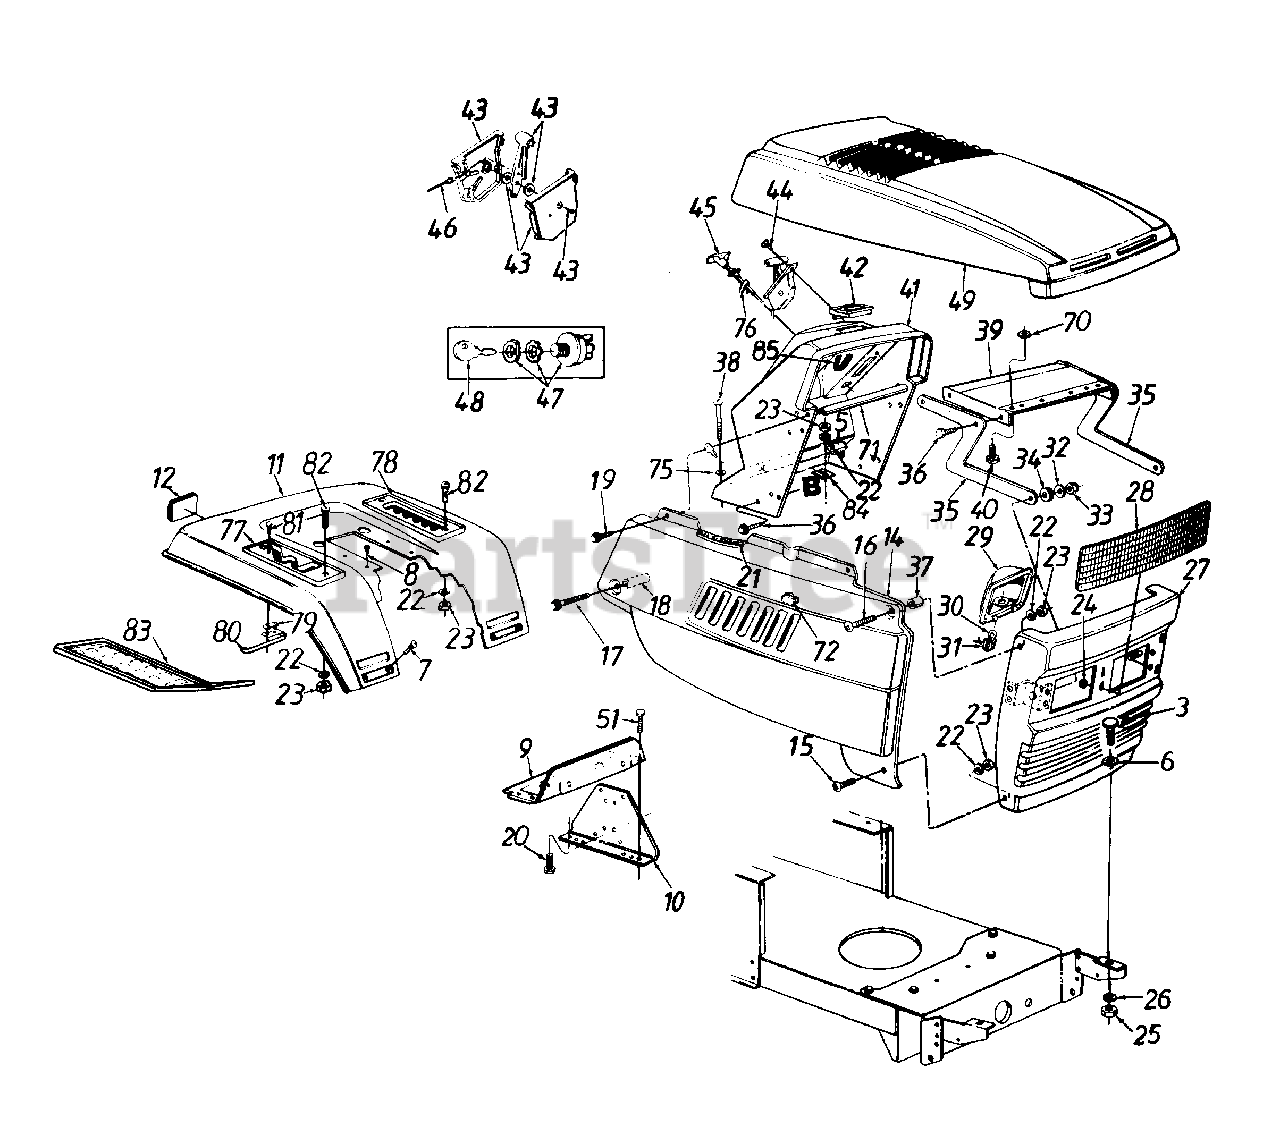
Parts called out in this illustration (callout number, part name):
3	Hex Bolt 5/16-18 x .75" Lg.
5	Light Switch
6	Fl-Wash. .344" I.D. x 1" O.D.
7	Carriage Bolt 1/4-20 x .5" Lg.
8	Hex Wash. Hd. Tap Scr. 5/16 x .75" Lg.
9	Support Bracket
14	Side Panel - R.H.
15	Truss Mach. Scr. 1/4-20 x .5" Lg.
16	Truss Mach. Scr. 1/4-20 x 1.0" Lg.
17	Hex Wash. TT-Tap Scr. 1/4-20 x 1.75" Lg.
18	Spacer .26" I.D. x 1.32"
19	Hex Rolling tap Scr. 1/4-20 x .75" Lg
20	Hex Bolt 1/4-20 x .62" Lg.
21	Trim Strip - 18" Lg.
22	L-Wash. 1/4" I.D.
23	Hex Nut 1/4-20 Thd
24	Speed Nut 5/16" Thd.
29	Headlamp Housing
30	Headlamp
31	Twist Lock Lamp Socket
32	Bell-Wash. .345" I.D. x .88"
33	Hex L-Nut 5/16-18 Thd.
34	Rubber Washer
37	Spacer .262" I.D. x .31"
38	Carriage Bolt 1/4-20 x 1.25" Lg.
41	Dash
42	Ammeter
43	Throttle Control Box Ass'y.
44	Mach. Scr. #10 x .44" Lg.
45	Choke Control
46	Throttle Control Wire
47	Ignition Switch
48	Ignition Key
49	Hood
51	Hex Wash. Hd. B-Tap Scr. 5/16-18 x .5" Lg.
70	Fl-Wash. .406" I.D. x .812" O.D.
71	Grille Support Tube
75	Retaining Nut
76	Choke Retainer
77	Forward/Reverse Index Brkt.
78	7-Speed Index Brkt.
79	Insulator Nut Plate
80	Reverse Safety Switch
81	Hex Wash. Hd. AB-Tap Scr. #8 x .5" Lg.
82	Truss Mach. Scr. 1/4-20 x .75" Lg.
83	Rubber Foot Pad - L.H.
84	Dash Fastening Tab
85	Cable Tie
